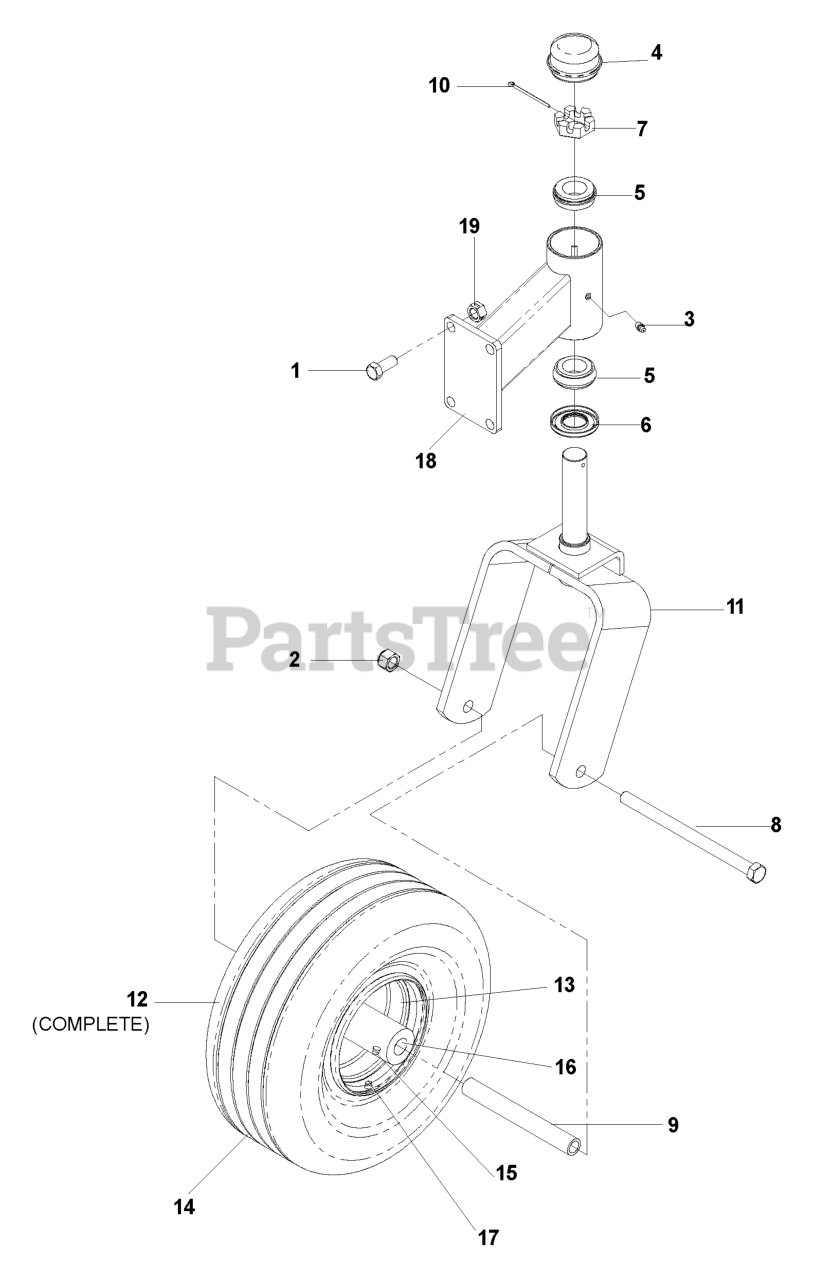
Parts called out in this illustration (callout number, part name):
1	HCS 7/16-14 X 1 GR 5 ZD
2	NUT 1/2-13 HEX NYLOC ZD
3	ZERK
4	GREASE CAP
5	TAPERED ROLLER BRG
7	NUT 1"C HEX SLOTTED
8	SCREW 1/2C X 7 1/2 HEX CAP
9	SPACER, CASTER
10	COTTER PIN 1/8 X 2
11	CASTER YOKE ORANGE
12	TIRE.ASSEM.13X5-6.SMOOTH.SILVE
13	RIM
14	TIRE - FRONT
15	ZERK 1/8 NPT
16	BEARING RETAINER
17	VALVE STEM TR-412
18	CASTER ARM, ORG
19	NUT 7/16C CENTERLOCK
